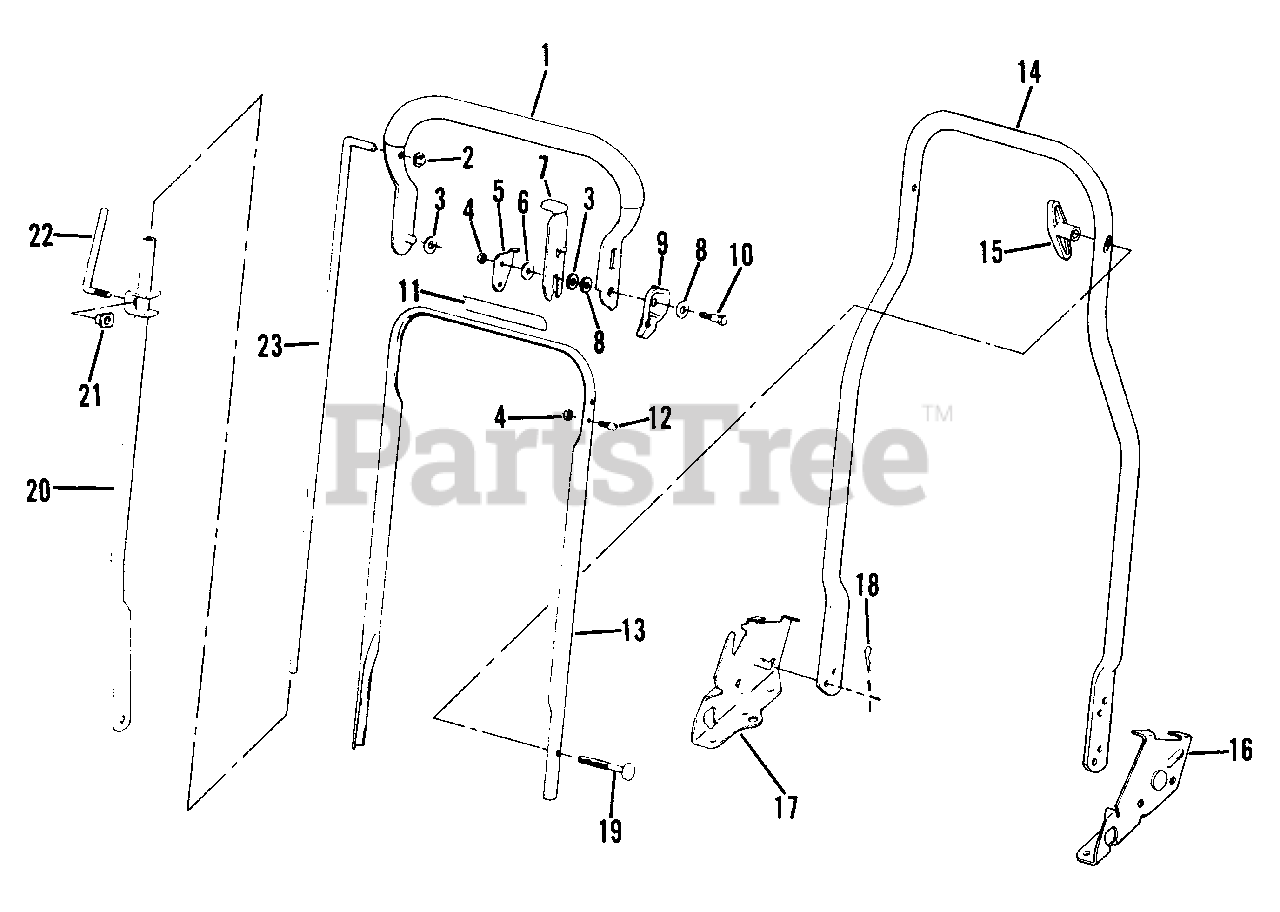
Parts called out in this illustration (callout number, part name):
1	Handle & Grip Assembly
2	Nut
3	Washer
4	Nut-Lock
5	Stop-Handle
6	Washer
7	Lever-Lockout
8	Washer
9	Guard-Lever
10	Bolt-Shoulder
11	Decal
12	Screw-Stop
13	Handle-Center
14	Handle Section-Bottom
15	Knob
16	Bracket-Handle L.H.
17	Bracket-Handle R.H.
18	Hair Pin
19	Screw
20	Control Lever Assembly
21	Nut
22	Screw
23	Control Rod
